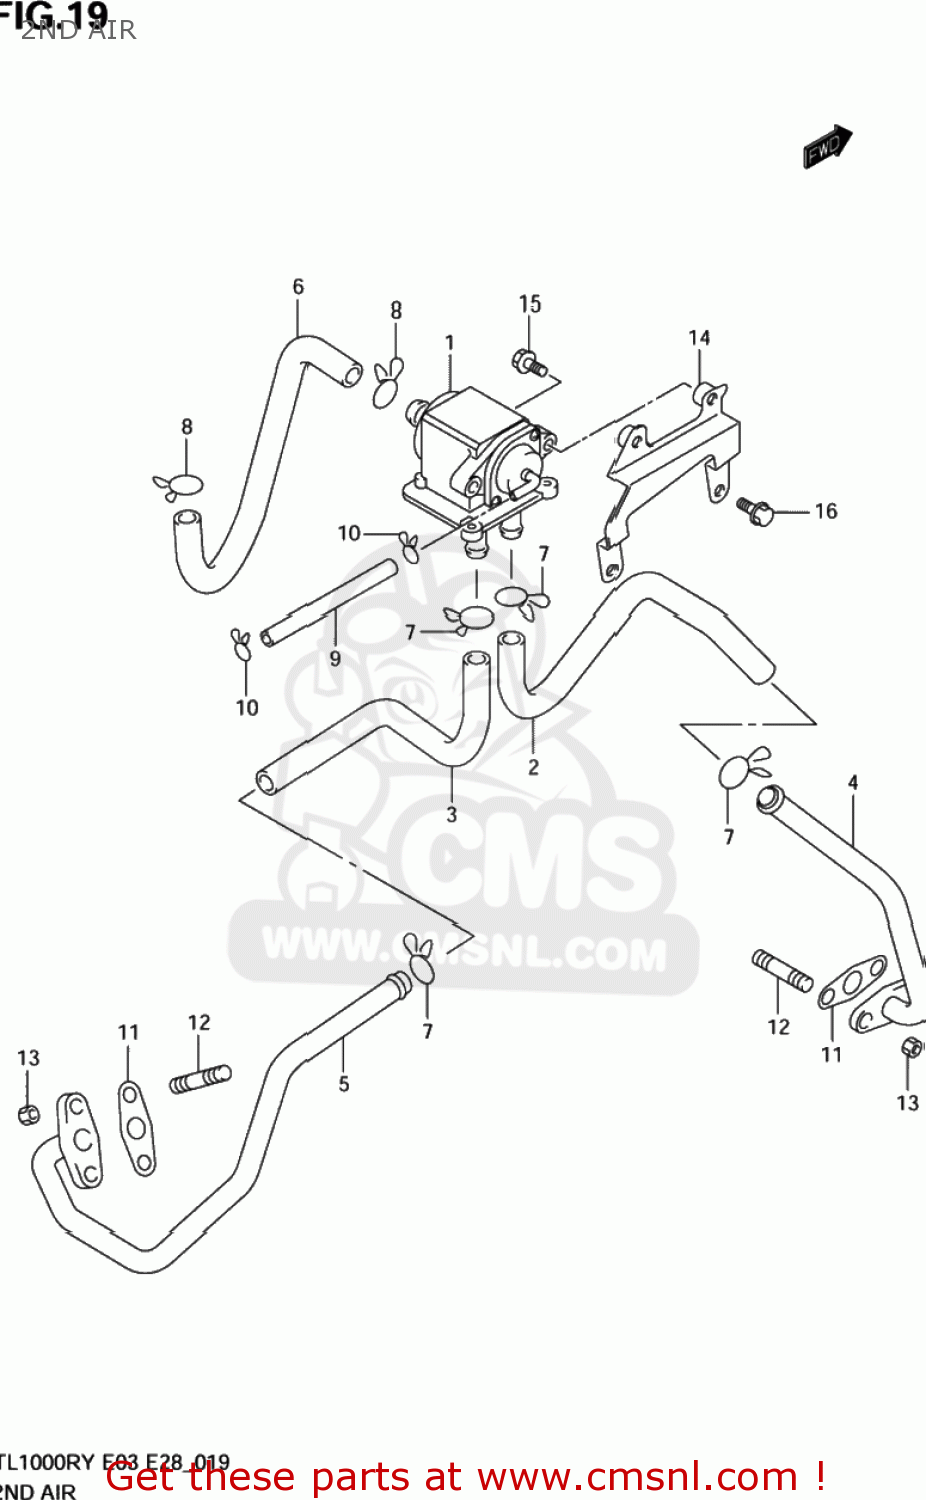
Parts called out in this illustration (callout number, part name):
1	VALVE ASSEMBLY,SECOND AIR
2	HOSE,2ND AIR VALVE FR
3	HOSE,2ND AIR VALVE RR
4	PIPE COMP,SECOND AIR,FRONT
5	PIPE,2ND AIR RR
6	HOSE,2ND AIR CLEANER
7	CLIP
8	CLIP
9	HOSE(4X7X600)
10	CLIP
11	GASKET,2ND AIR PIPE (NAS)
12	STUD BOLT
13	NUT
14	BRACKET,2ND AIR VALVE
15	BOLT,OIL FILLE
16	BOLT
